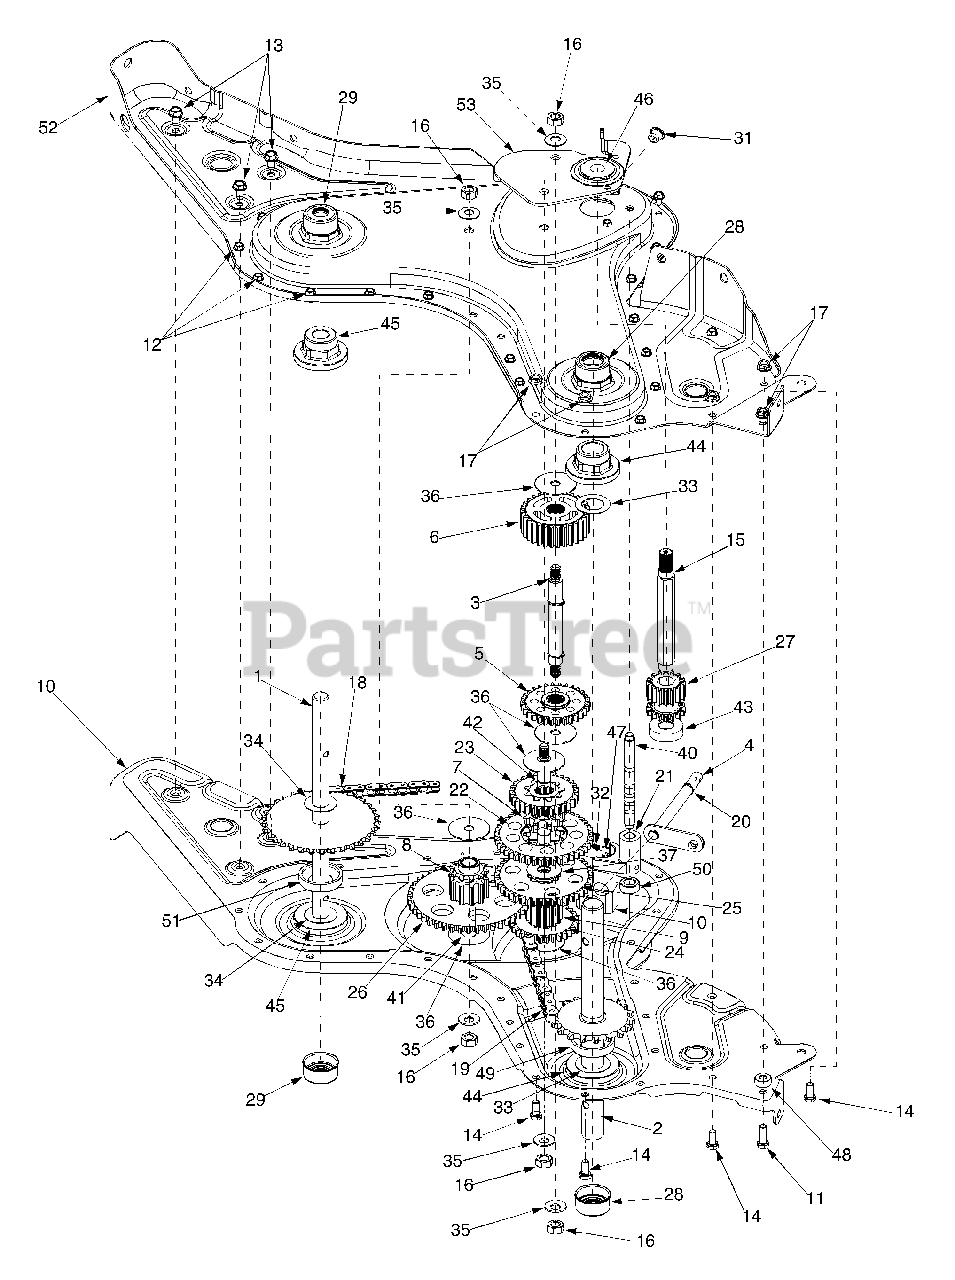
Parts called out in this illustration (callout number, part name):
1	Wheel Shaft Ass'y 33T
2	Tine Shaft Ass'y: 18T
3	Jack Shaft Ass'y
4	Input Shaft Ass'y
5	Rev. Idler Gear Ass'y: 30T
6	Tine Idler Gear Ass'y: 30T
7	Tine Input Sprocket Ass'y: 9T
8	Wheel Input Sprocket Ass'y: 10T
9	Gear Ass'y: 11T
10	R.H. Housing Ass'y
11	Hex Bolt 5/16-18 x 1" Lg.
12	Hex S-Tap Scr. 1/4- 20 x.5"
13	Hex S-Tap Scr. 5/16-18 x.625"
14	Hex Bolt 5/16-18 x.75"
15	Input Shaft
16	Hex Nut 7/16-20
17	Flange Nut 5/16-18
18	#420 Chain 1/2 Pitch x 50 Links
19	#50 Chain 5/8 Pitch x 54 Links
20	Snap Ring
21	Shifting Fork
22	Spur Gear 44T
23	Spur Gear 30T
24	Spur Gear 30T
25	Spur Gear 44T
26	Spur Gear 44T
27	Spur Gear 16T
28	Seal 1.0 Shaft
29	Seal.75 Shaft
31	Taper Cap Ring
32	Compression Spring.50" Leg.
33	Thrust Wash. 1.03" I.D. X. 1.62"
34	Fl-Wash.76" I.D. x 1.5" O.D.
35	Bell-Wash .45" I.D. x 1.0"
36	Thrust Wash. .445 x 1.92 x .060
37	Fl-Wash. .635" I.D. x 1.59 O.D.
40	Detent Shaft 1/2" Dia.
41	Jack Shaft .625 x 2.385
42	Jack Shaft .625 x 5.0
43	Ball Bearing
44	Flange Bearing 1.0 x 2.5 x 1.38
45	Flange Bearing .75 x 2.5 x 1.38
46	Ball Bearing .6692 x 5745 x .466
47	Detent Ball .250
48	Spacer .315
49	Spacer 1.0 I.D x 2.0 O.D. x .440
50	Spacer .505 I.D. x .88 O.D. x .440
51	Spacer .75 x 2.0 x .50
52	L.H. Chain Case Ass'y
53	Gear Positioner Bracket
